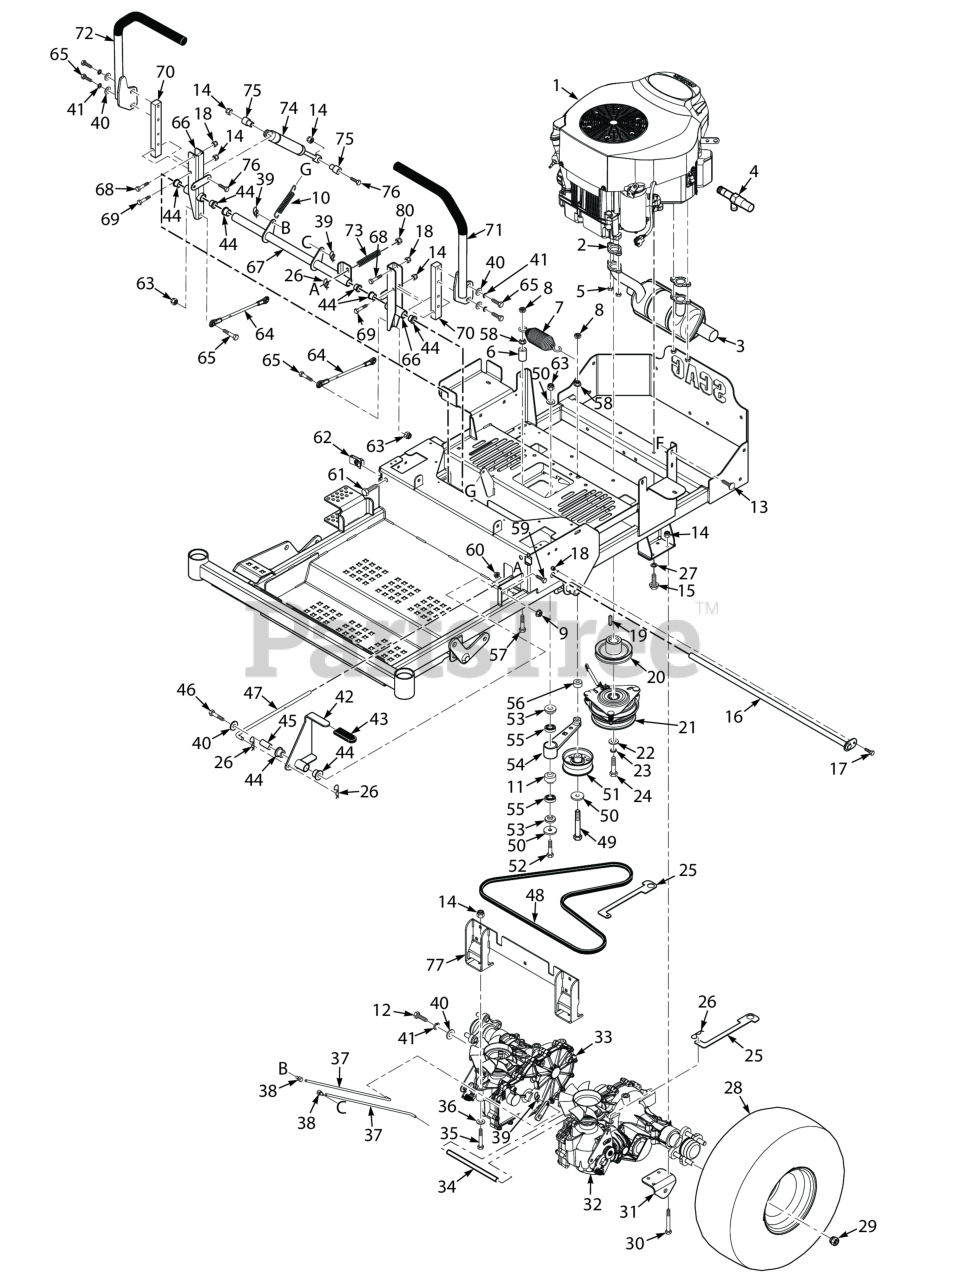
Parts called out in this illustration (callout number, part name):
1	Engine, Kawasaki 21FR
2	Gasket, Exhaust
3	Muffler, Kawasaki FR651V & FR691V
4	Oil Drain, Kawasaki
5	Nut, M8 x 1.25 Hex Special
6	Spacer, Idler Pulley - SFZ52
7	Spring, Transmission Drive
8	Bolt, Hex Head 3/8-16 x 1" Ser. Flg.
9	Nut, Flange Elastic Stop Nut, 3/8-16
10	Spring, Deck Latch
11	Spacer, Bearing
12	Bolt, Hex Head 3/8-16 x 2-1/4" - 61"
13	Serr. Fl. Hex Head CPSCR, 1/4-20 x 3/4"
14	HEX NUT, ELASTIC STOP LOCK, 5/16-18
15	Bolt, Hex Head 3/8-16 x 1-1/4", Kawasaki FX / FT & FT-EFI
16	Shaft Weldment, Control Arm
17	BOLT, HEX HEAD, 1/4-20 X 5/8
18	HEX, NUT, ELASTIC STOP LOCK, 1/4-20
19	Key, 1/4 x 1/4 x 1.25" Pulley Mtg.
20	Pulley, 4-1/2" - 1" Bore
21	Electric Clutch Assembly
22	Flatwasher, 7/16-.469 x 1.75 x .25 (48, 52)
23	Lockwasher, 7/16� Spring
24	Bolt, Hex Head 7/16-20 x 3¼" w/Patch
25	Lever, Dump Valve
26	HAIR PIN, .08 DIAMETER X 1-3/16"
27	Lockwasher, 3/8" Spring, Kawasaki FX / FT & FT-EFI / B&S 32BV
28	Wheel Assembly (48, 52)
29	Wheel Nut, 1/2-20 x 13/16
30	Bolt, Hex Head 5/16-18 x 3.00"
31	Bracket, Push Arm Link
32	Transaxle, LH - SZL
33	Transaxle, RH - SZL
34	Spacer
35	BOLT, HEX HEAD, 5/16-18 X 2-1/4
36	Flatwasher, 5/16-.375 x .875 x .083 (35BV & 37BV-EFI)
37	Rod, Brake
38	Joint, Swivel
39	Pin, Rue Cotter 3/8" Diameter
40	Flatwasher, 3/8" Special (.391 x .938 x .105)
41	Lockwasher, 3/8" Spring, Kawasaki FX / FT & FT-EFI / B&S 32BV
42	Brake Lever Assembly
43	Grip, Brake Handle
44	Bearing
45	Pivot, Brake Lever
46	Capscrew, Hex Head 3/8-16 x 2-1/2"
47	Rod, Upper Brake Linkage
48	Belt, Transmission -SZL
49	Capscrew, Hex Head 3/8-16 x 3-3/4"
50	Flatwasher, 3/8 (.391 x .938 x .105 HD) Grade 8
51	Pulley, 3-1/2" Dia.
52	Bolt, Hex Head 3/8-16 x 3" - 52"
53	Spacer, Controls
54	Trans. Idler Arm Assy. (Includes 24, 79)
55	BEARINGS, BALL, NEUTRAL RETURN
56	Spacer, Idler Pulley - SFZ61
57	Capscrew, Hex Head 3/8-16 x 2.0"
58	NUT, 3/8-16 SERRATED FLANGE HEX HEAD
59	Capscrew, Hex Head 1/4-20 x 1"
60	NUT, 1/4-20 SERRATED FLANGE HEX HEAD
61	Bolt, Hex Head 3/8-16 x 2-1/2" Soecial Lock
62	U-Nut, 3/8-16
63	HEX NUT, ELASTIC STOP LOCK, 3/8-16
64	Linkage, Pump
65	Bolt, Hex Head 3/8-16 x 1-1/4", Kawasaki FX / FT & FT-EFI
66	Control Arm Assembly
67	Bellcrank Assembly (incl. 44)
68	Bolt, Hex Head, 1/4-20 x 1-1/4"
69	Bolt, Hex Head 5/16-18 x 1-1/2" - Front
70	Bar, Control Lever
71	Handlebar w/Grip
72	Handlebar w/Grip
73	Spring, Brake
74	Damper, Steering
75	Spacer, Pump Dampener
76	Bolt, Hex Head 5/16-18 x 1-1/2" (Right Front Engine Mounting, Briggs and Kohler Only)
77	Mounting Weldment, Axle - Hydro-Gear
